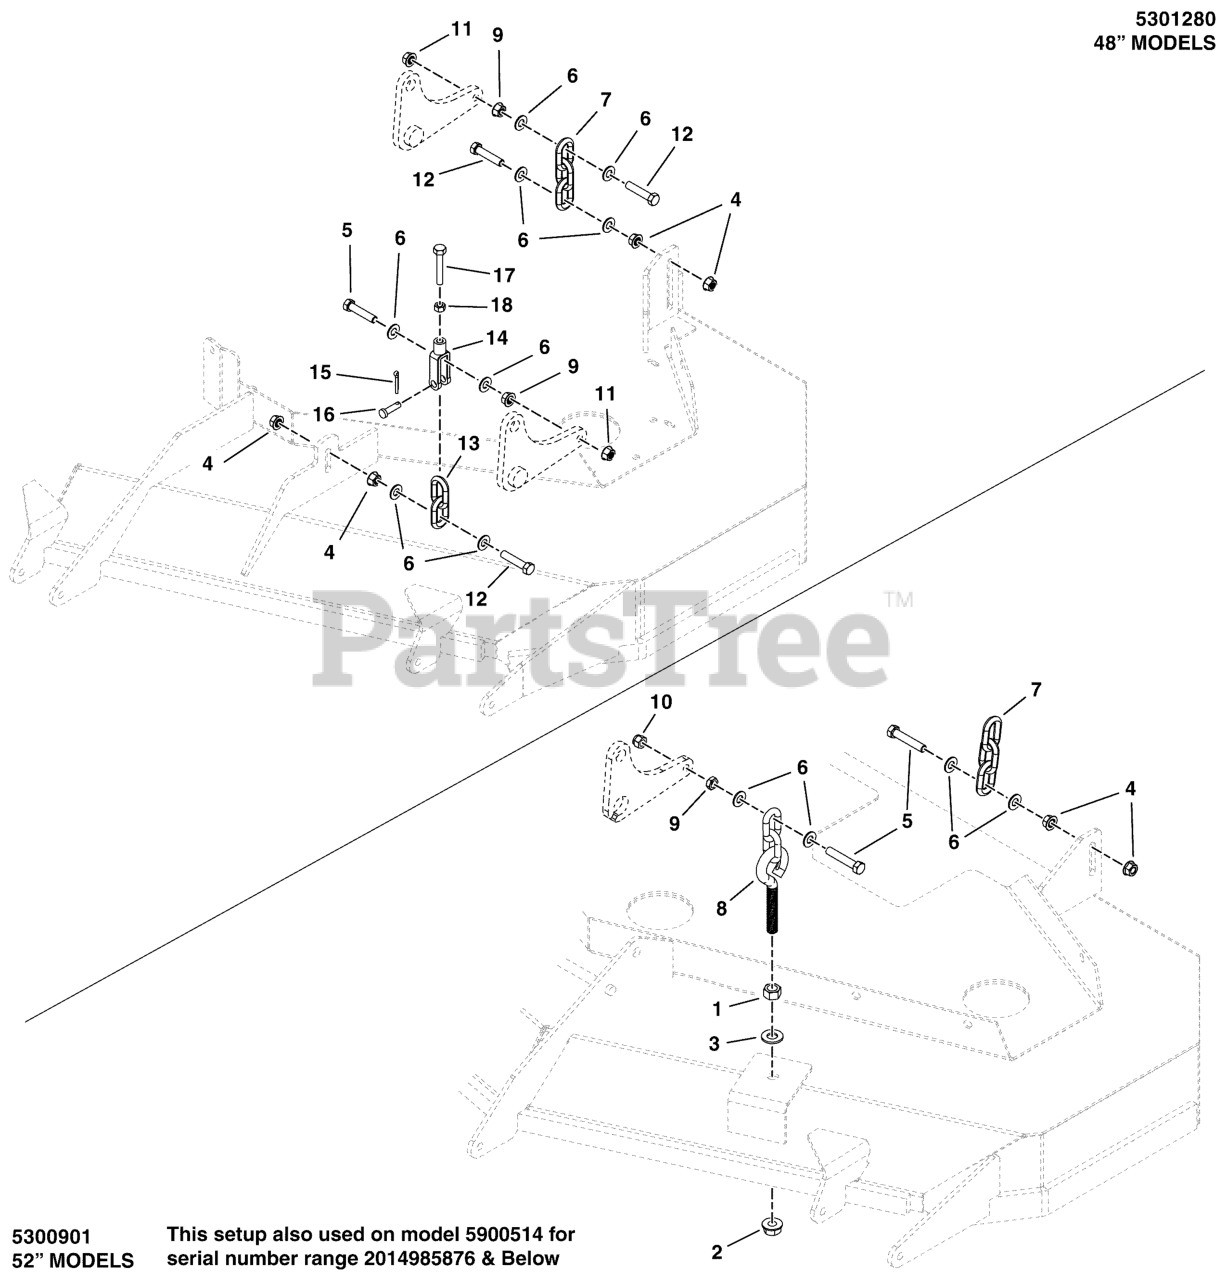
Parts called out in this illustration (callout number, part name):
1	NUT, 1/2-13 HEX
2	NUT, Hex Flange, Nylock, 1/2-13
3	WASHER, 1/2 SAE
4	NUT, 3/8-16 HEX SERRATED FLANGE
5	BOLT, 3/8-16 X 2, GD5, CZ
6	WASHER, 3/8 SAE
7	CHAIN, 5/16 GD30, 3 LINKS
8	HANGER, FRONT DECK-2LINK, 5.5" EB
9	NUT, 3/8-16 HEX JAM
10	NUT, 3/8-16 HEX NYLON LOCK
11	NUT, 3/8-16 HEX NYLOCK FLANGE
12	BOLT, 3/8-16 X 1-3/4" GD5 CZ
13	HANGER, FRONT DECK - 2 LINK
14	CLEVIS, 5/16-18, 3/8 PIN HOLE
15	PIN, CLEVIS, 3/8 X 1-1/8
16	PIN, 3/32 X .750M COT, ZINC/CLEAR
17	BOLT, 5/16-18 X 2 GD5 TFL
18	NUT, 5/16-18 HEX JAM
